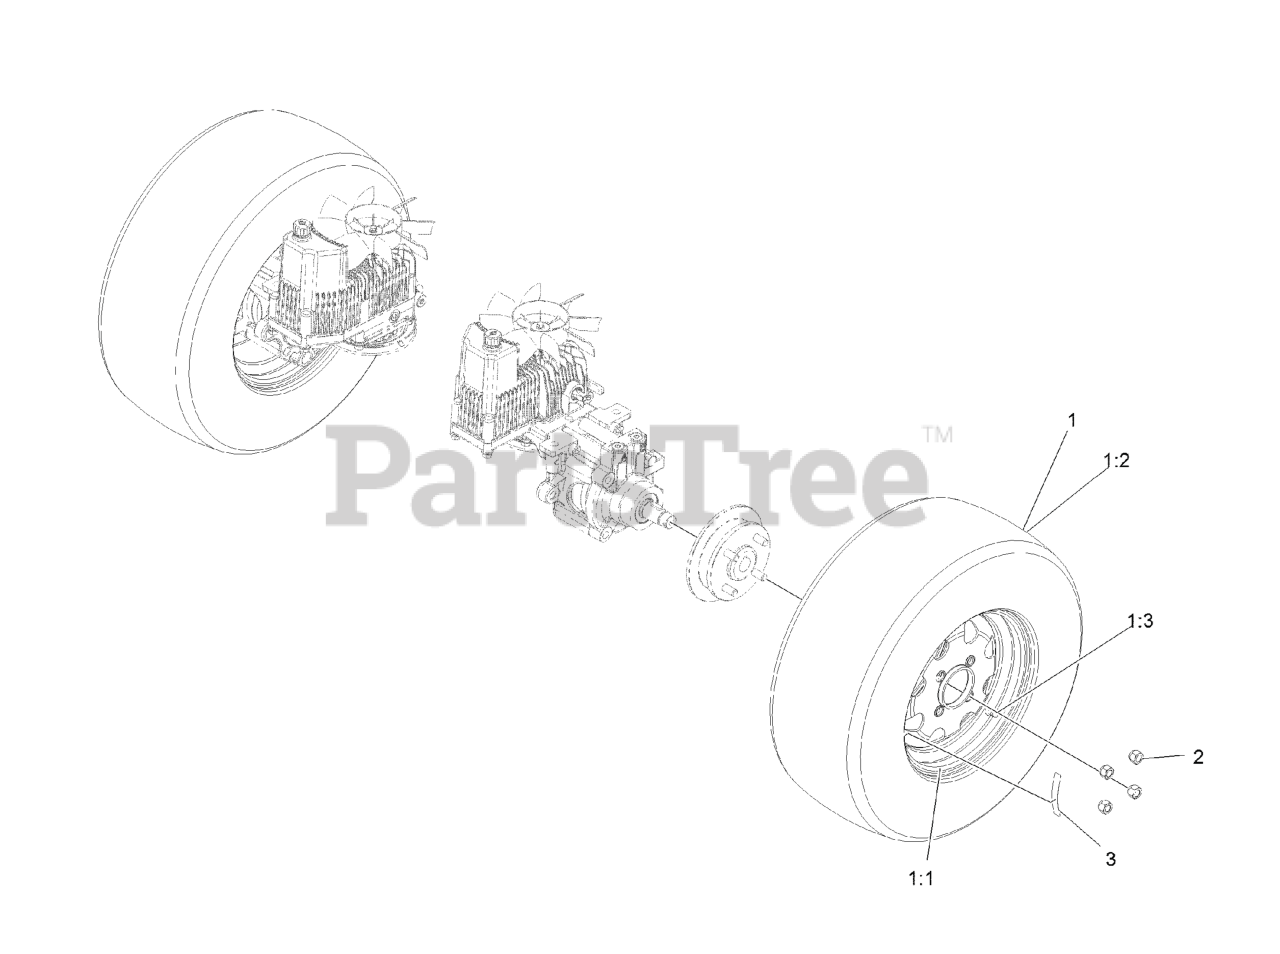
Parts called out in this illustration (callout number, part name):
1	WHEEL AND TIRE ASM
1:1	RIM ASM
1:2	TIRE
1:3	Stem-Valve
2	NUT-LUG
3	DECAL-TORQUE, WHEEL HUB LUG
